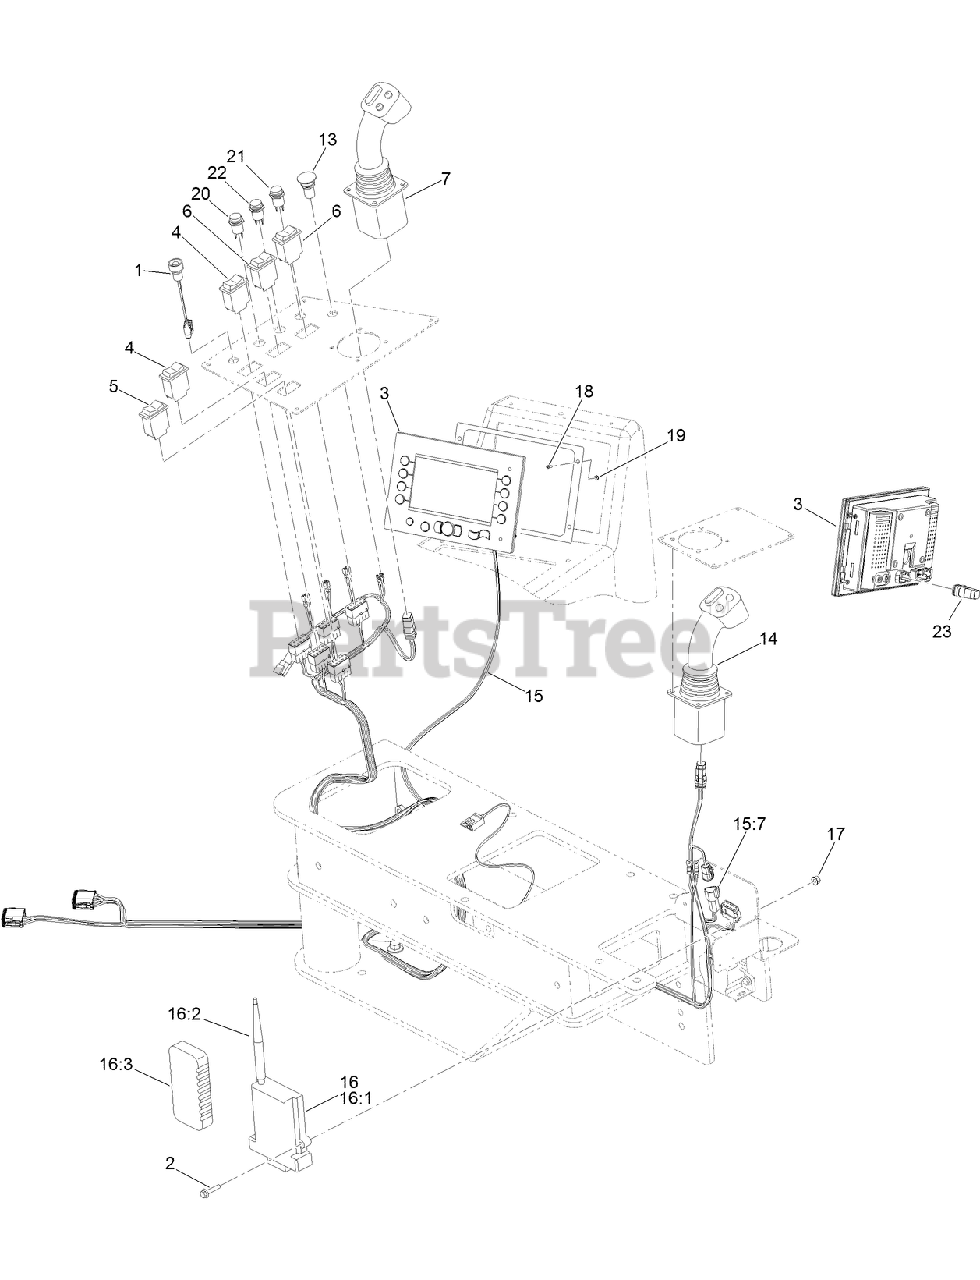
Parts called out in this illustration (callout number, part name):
1	SWITCH-START, GREEN BUTTON
2	SCREW-HHF
3	DISPLAY-DP610TM, UNPROGRAMMED
4	SWITCH-ROCKER, 2 POLE (ON/OFF)
5	SWITCH-ROCKER, 2 POLE
6	SWITCH-ROCKER, 1 POLE (ON)OFF/ON(OFF)
7	JOYSTICK-MODIFIED (LEFT HAND)
13	BUTTON-PUSH, RED MUSHROOM
14	JOYSTICK-CARRIAGE
15	HARNESS-WIRE, OPERATOR
15:7	RESISTOR-120 OHM
16	STANDARD EXIT SIDE LOCKOUT
16:1	BASE UNIT-LOCKOUT
16:2	ANTENNA-LOCKOUT
16:3	HANDHELD-LOCKOUT
17	NUT-FLANGE, NI
18	SCREW-PH
19	NUT-LOCK, NI
20	LAMP-INDICATOR, LED
21	LAMP-INDICATOR, LED
22	LAMP-INDICATOR, LED
